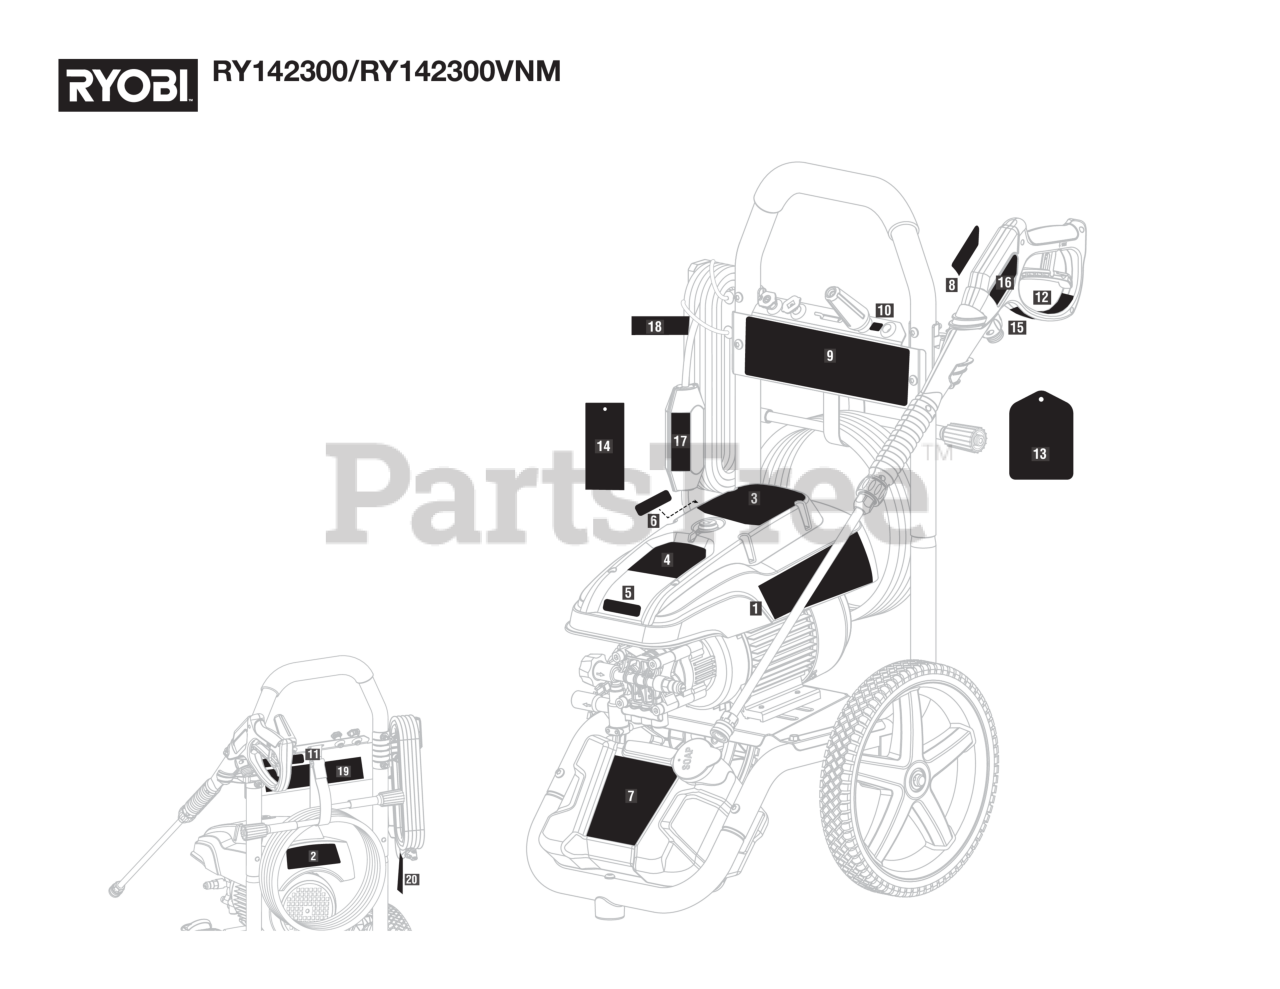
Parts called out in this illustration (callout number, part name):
1	Danger Label
2	Regulatory Danger Label
3	Performance/Induction Label
4	Brushless Label
5	Logo Label
6	Try Another Outlet Label
7	Detergent Tank Label
8	Trigger Handle Logo Label
9	Performance Label
10	Nozzle Storage Label
11	Inquires Label (Ryobi)
12	Label (Trigger Handle Warning, French & Spanish)
13	Nozzle Hangtag (PS141913)
14	Danger Hangtag (Spanish)
15	Rating Label
16	Trigger Handle Warning Label (English)
17	Power Cord Label
18	Cordwrap Warning Label
19	Quick Start Label
20	Outlet Cord Wrap Label
